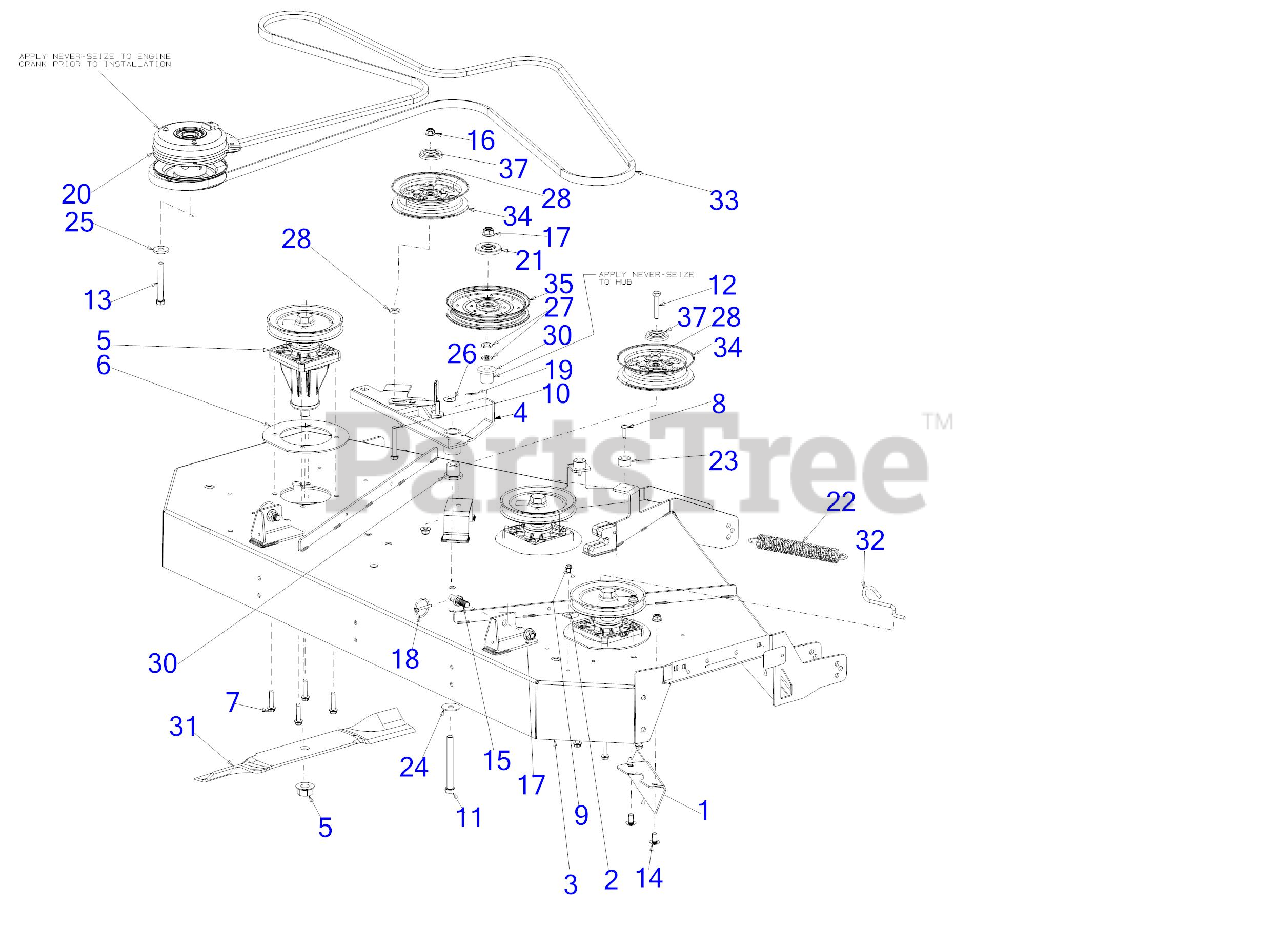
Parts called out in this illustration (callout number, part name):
1	CHUTE BAFFLE
2	HOOK RETAINER BRACKET
3	60" FAB DECK SHELL
4	IDLER ARM ASSEMBLY
5	SPINDLE ASSEMBLY
7	SCREW 5/16-18 x 1.50
8	SCREW 1/4-20 x 1.0
9	SCREW 1/4-20 X.500
10	HEX SCREW-3/8-16X2.5 GR5
11	SCREW 1/2-13 x 4.5 GR 5
12	SCREW 3/8-16 x 2.0 GR5
13	SCREW 7/16-20 x 3.25 GR5
14	CARRIAGE BOLT 3/8-16 x .75
15	DECK PIN
18	LYNCH PIN
19	COTTER PIN 3/32
20	ELECTRIC PTO CLUTCH
21	PULLEY CAP 1/2"
22	EXTENSION SPRING
23	BUMPER
24	WASHER .51 x 1.5 x .07
25	FLAT WASHER .445 x 1.248 x .170
26	FLAT WASHER
27	FLAT WASHER
28	FLAT WASHER
30	SHOULDER SPACER
31	21" BLADE (HI LIFT)
32	DECK SPRING HOOK
33	DECK BELT B x 161.75
34	IDLER PULLEY 5.0" DIA
35	IDLER PULLEY 6.0" DIA
37	IDLER PULLEY CAP
